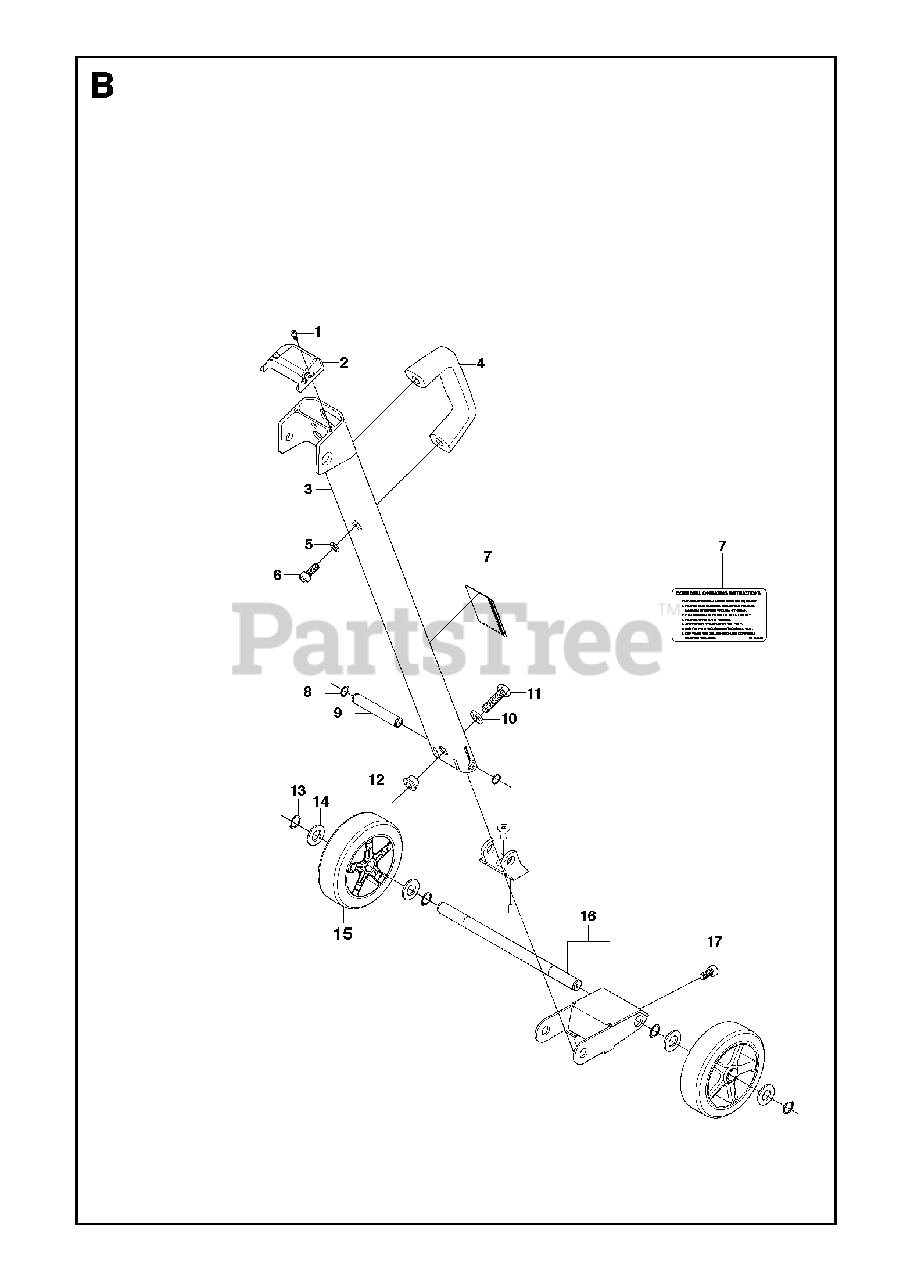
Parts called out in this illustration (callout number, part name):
5	WASHER
10	WASHER
13	CIRCLIPNot for Single Speed
14	WASHERNot for Single Speed
15	WHEELNot for Single Speed
16	WHEELNot for Single Speed
17	SCREW IHSCMNot for Single Speed
